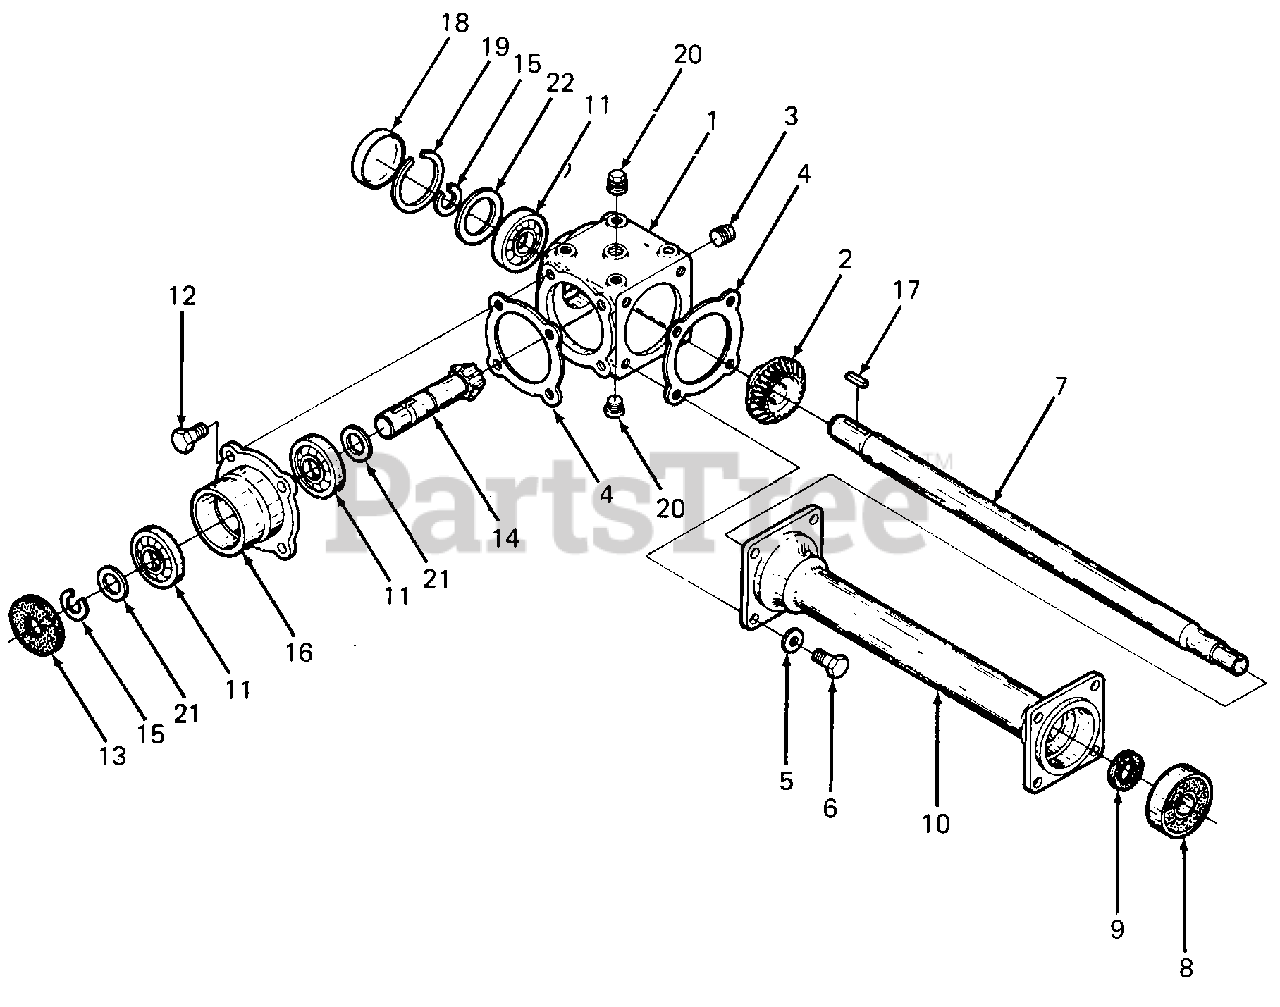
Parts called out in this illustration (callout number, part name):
2	Crownwheel 25 Tooth
6	Screw, Hex Cap, M10 X 20 mm Lg GR 8.8
9	Seal, Oil, 30 mm X 47 mm X 7 mm
10	Extension
12	Screw, Hex Cap, M10 X 22 Lg GR 8.8
13	Seal, Oil, 25 mm X 62 mm X 7 mm
14	Pinion, 9 Tooth Bevel
15	External Circlip
16	Extension
17	Key, Parallel, 8 mm X 7 mm X 25 mm
19	Internal Circlip
21	Shim, .3 mm Thick
22	Shim, .3 mm Thick
